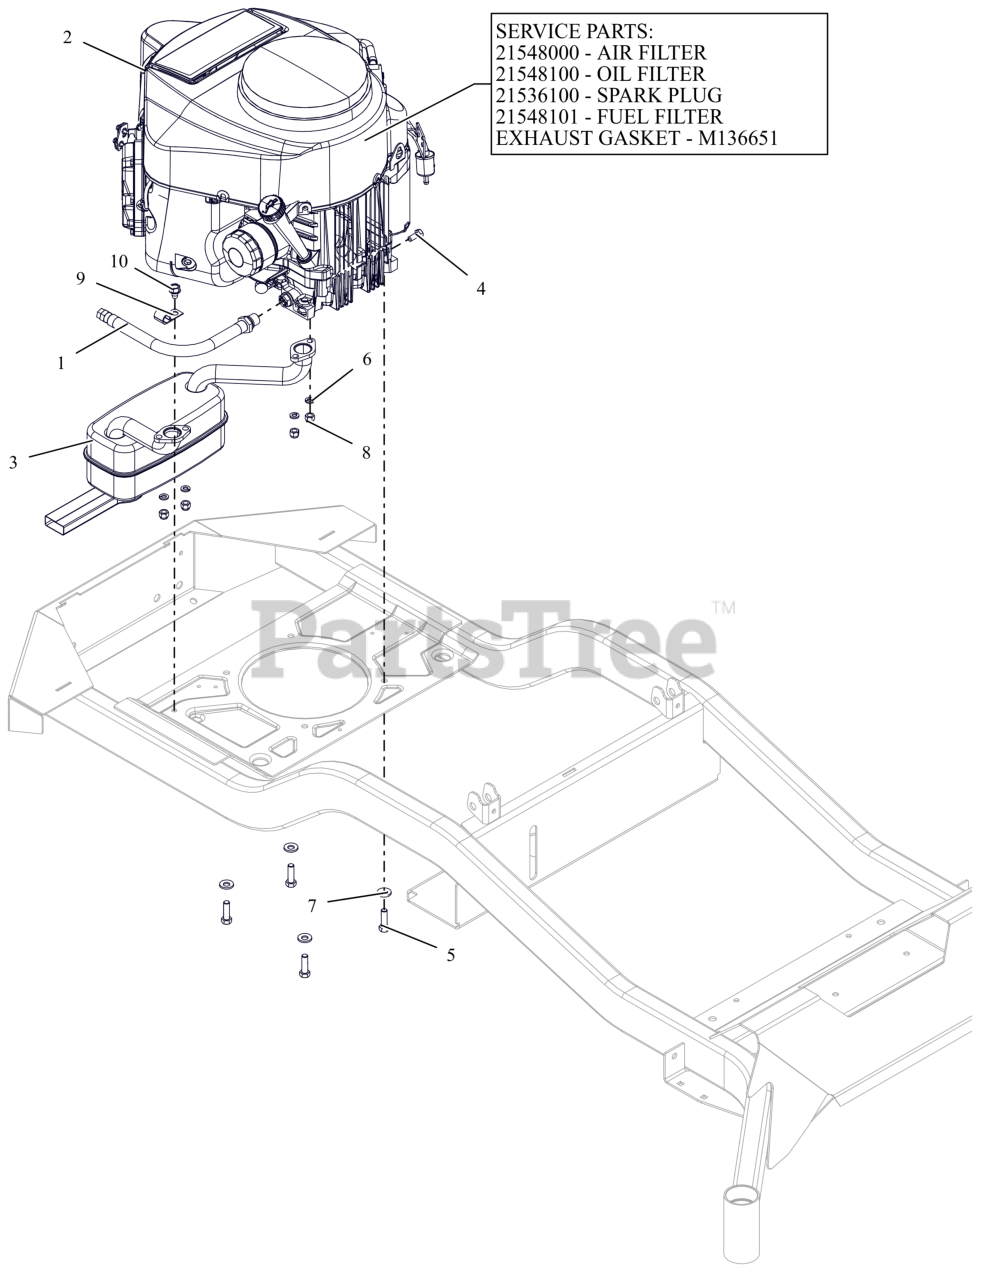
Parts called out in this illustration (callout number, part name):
1	HOSE, OIL DRAIN
2	ENGINE, KAWASAKI FR730 24HP
2	AIR FILTER, KAWASAKI FR
2	OIL FILTER, KAWASAKI FR
2	PLUG, SPARK
2	FUEL FILTER-KAWASAKI FR
2	GASKET, MUFFLER #
3	MUFFLER, KAWASAKI
4	BLT, HEX M8-1.25X20 G8.8 ZCC
5	BLT, HEX .38-16X1.25 G5 ZCC NT
6	WSHR,LK-REG .312X.078 ZCC
7	WASHER, 3/8" SPRING DISC
8	NUT, LK-CTR-JAM M8-1.25 GR8.8 ZC120
9	J-CLAMP
10	SCR,TAP .375-16X.50 HWH TR ZCC
